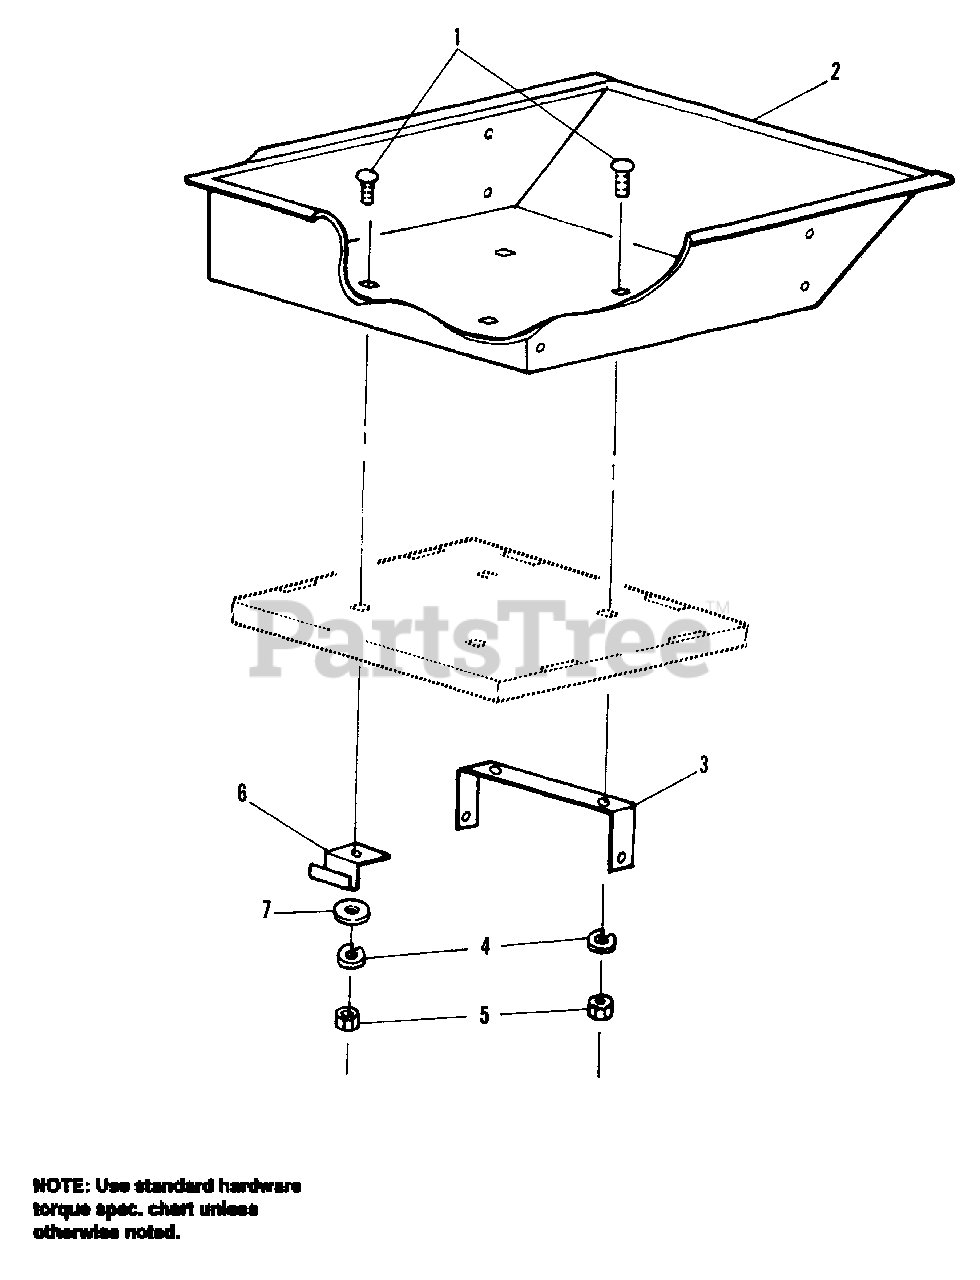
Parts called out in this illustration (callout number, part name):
1	*BOLT, Carriage, 5/16-18 x 3/4
2	STEEL TILT-HOPPER
3	*BRACKET, Pivot, Platform
4	*LOCKWASHER, 5/16
5	*NUT, Hex, 5/16-18
6	*CLIP, Latch Rod
7	WASHER, 5/16
